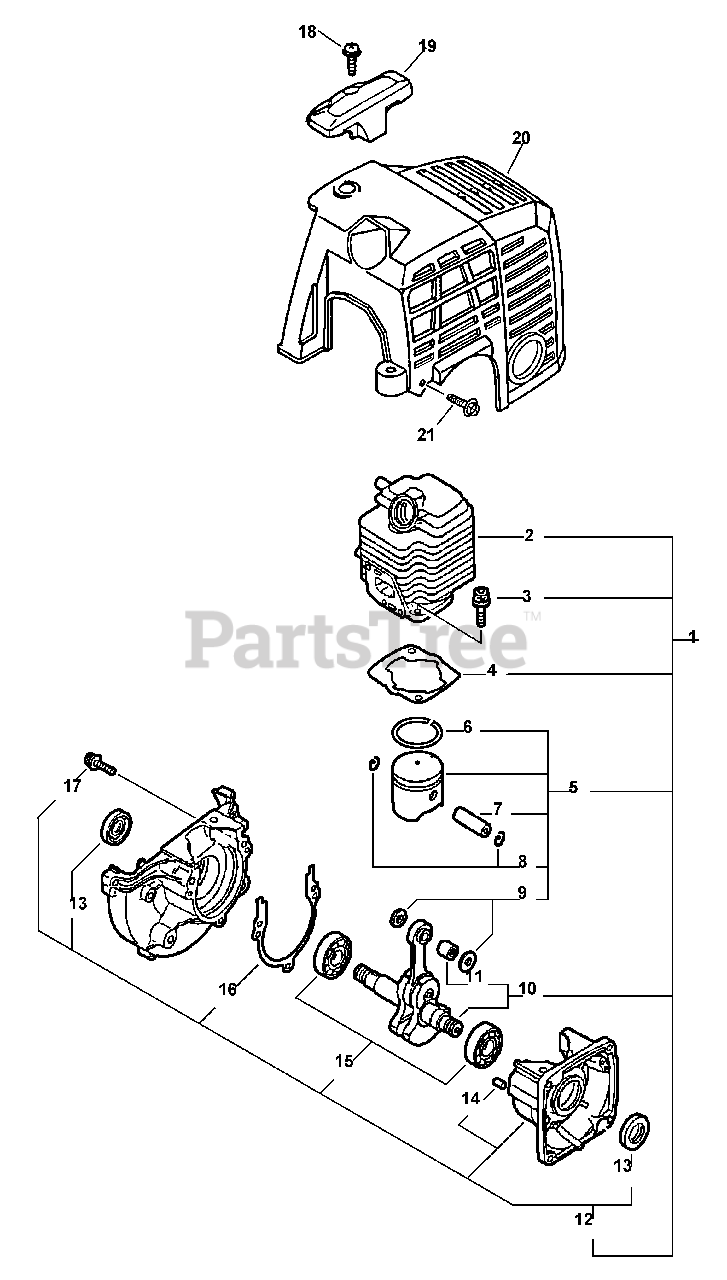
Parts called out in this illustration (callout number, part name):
1	Short Block
2	Cylinder
3	Bolt 5x22
4	Gasket, Cylinder Base
5	Piston Kit
6	Ring, Piston
7	Pin, Piston
8	Circlip, Piston Pin
9	Spacer, Piston Pin
10	Crankshaft Asy
11	Bearing, Needle
12	Crankcase Kit
13	Oilseal
14	Pin, Dowel
15	Bearing, Ball 6201
16	Gasket, Crankcase
17	Screw 5x28
18	Screw 5x16
19	Guard, Top
20	Cover, Cylinder
21	Screw 4x16
